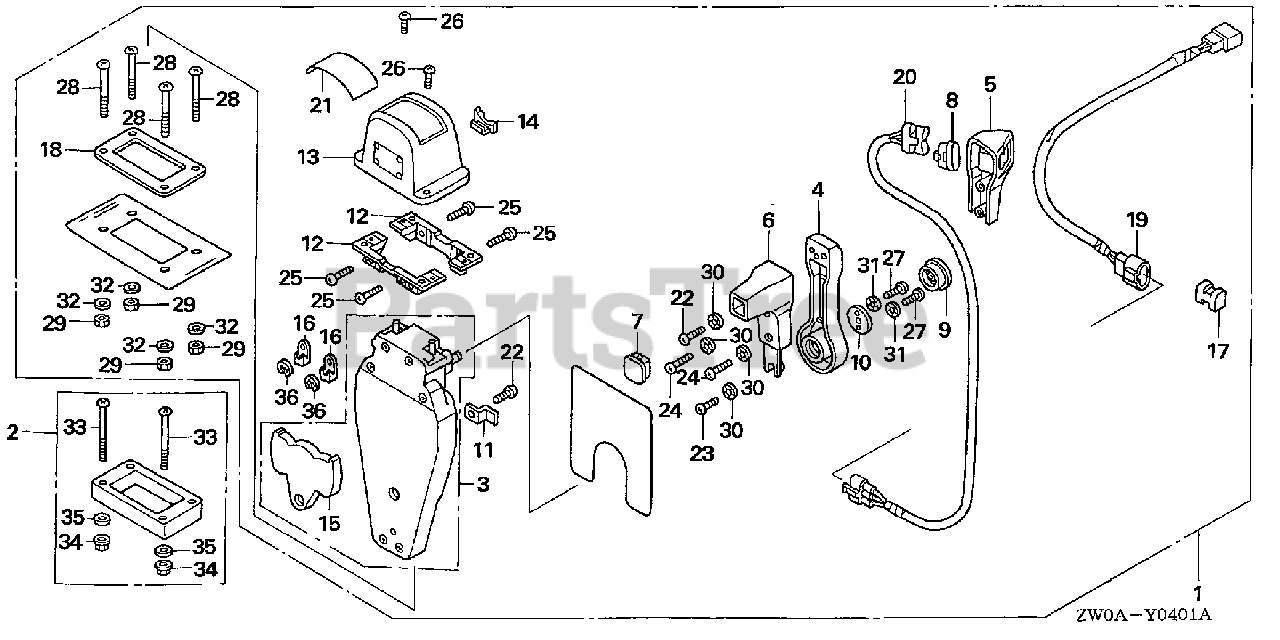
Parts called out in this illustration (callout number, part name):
1	BOX KIT, REMOTE CONTROL
2	SPACER KIT, REMOTE CONTROL BOX
3	HOUSING ASSY., R. (INNER)
4	HANDLE, REMOTE CONTROL
5	COVER, R. GRIP
6	GRIP, REMOTE CONTROL HANDLE
7	CAP, GRIP
8	CAP, SWITCH
9	BUTTON, THROTTLE
10	PLATE, HANDLE
11	PLATE, CABLE CLAMP
12	BRACKET, REMOTE CONTROL
13	HOUSING, REMOTE CONTROL BOX
14	HOUSING, LEAD
15	PLATE, DWELL
16	TERMINAL, CABLE
17	SPACER, CABLE CLAMP
18	GASKET, SINGLE
19	SUB-HARNESS ASSY., POWER
20	SWITCH ASSY., POWER TRIM-TILT
21	MARK, REMOTE CONTROL (SINGLE)
22	SCREW, PAN (5X16)
23	SCREW, PAN (5X10)
24	SCREW, PAN (5X20)
25	SCREW, PAN (5X18)
26	SCREW, PAN (4X10)
27	SCREW, PAN (6X18)
28	SCREW, PAN (5X40)
29	NUT, HEX. (5MM)
30	WASHER, LOCK (5MM)
31	WASHER, LOCK (6MM)
32	WASHER, PLAIN (5MM)
33	SCREW, PAN (5X65)
34	NUT, HEX. (5MM)
35	WASHER, PLAIN (5MM)
36	E-RING (6MM)
